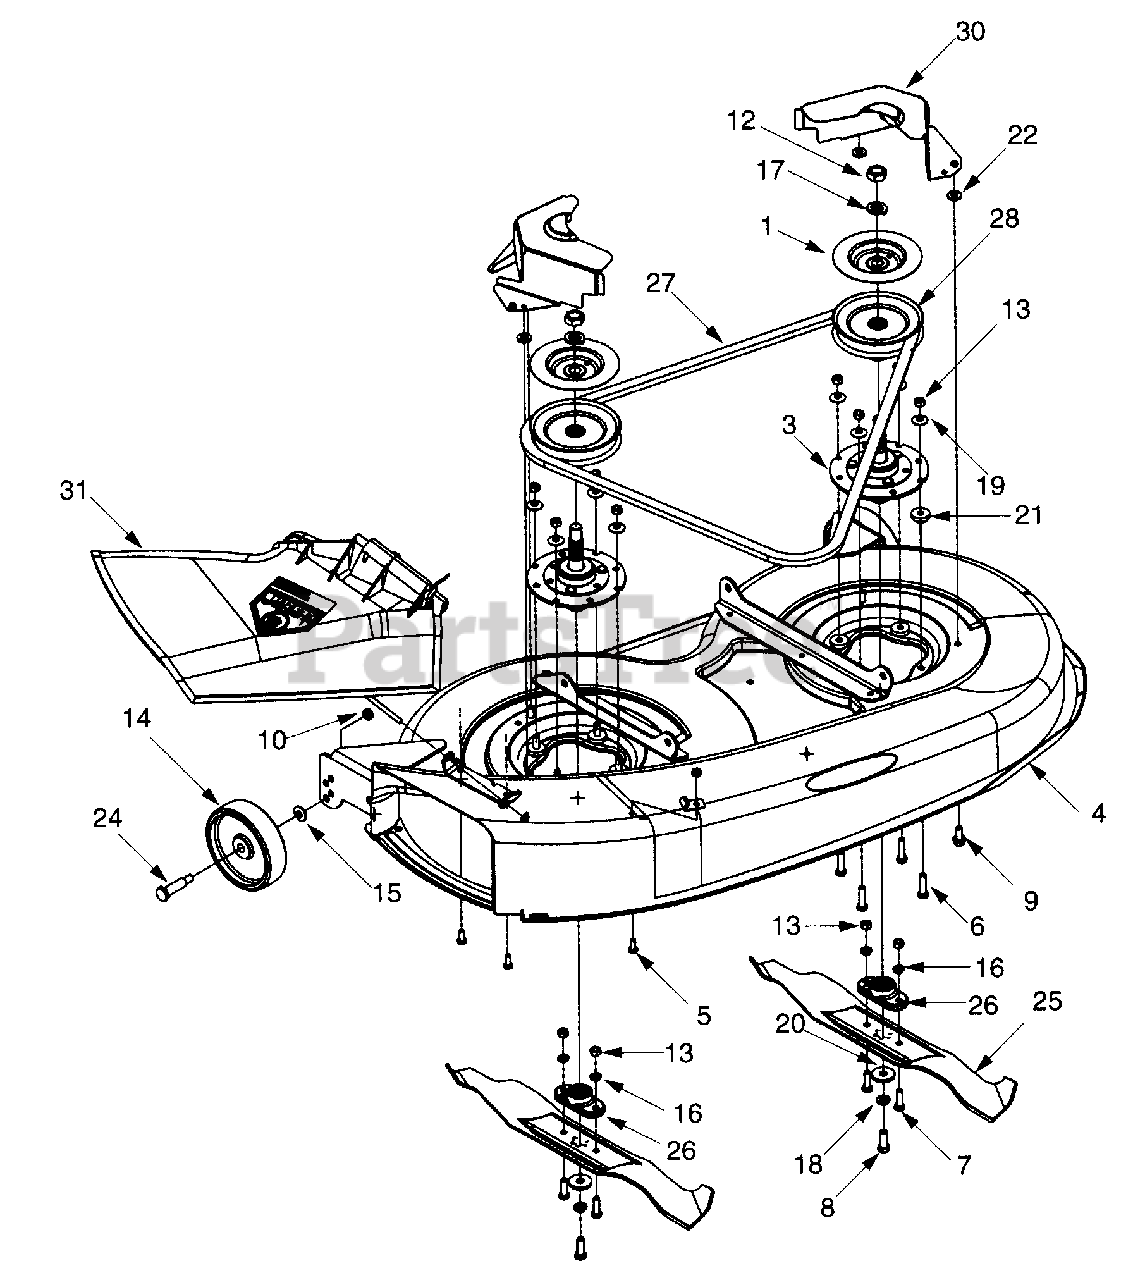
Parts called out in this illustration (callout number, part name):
1	Disc: Brake
3	Blade Spindle
6	Hex Cap Screw 5/16-24 x 1.25 Gr. 5
7	Hex Screw 5/16-24 x 1.0 Gr. 5 Sp.
8	Hex Screw 3/8-24 x 1.0 Gr. 5 Std.
9	Hex Wash. TT Screw 5/16-18 x .75
10	Jam Nut 3/8-16: Top Lock
12	Hex Jam Nut 5/8-18
13	Hex Nut 5/16-24 Gr. 5
14	Wheel Deck 5.0 x 1.38
15	Bell Washer .401 x .807 x .063
16	Lock Washer: 5/16 Regular Duty
17	Lock Washer: 5/8 Regular Duty
18	Lock Washer: 3/8 Heavy Duty
19	Bell Washer .345 I.D. x .88 O.D. x .06
20	Flat Washer 3/8 x 1.25 O.D.
21	Flange Washer .320 I.D. x .750 x .140
22	Flat Washer .344 x .75 x . 140
24	Shoulder Screw
25	Three in One Star Blade
26	Blade Adapter
27	V: Belt
28	Deck Pulley 5" Dia.
31	Chute Deflector: Deck, Deep Plastic
